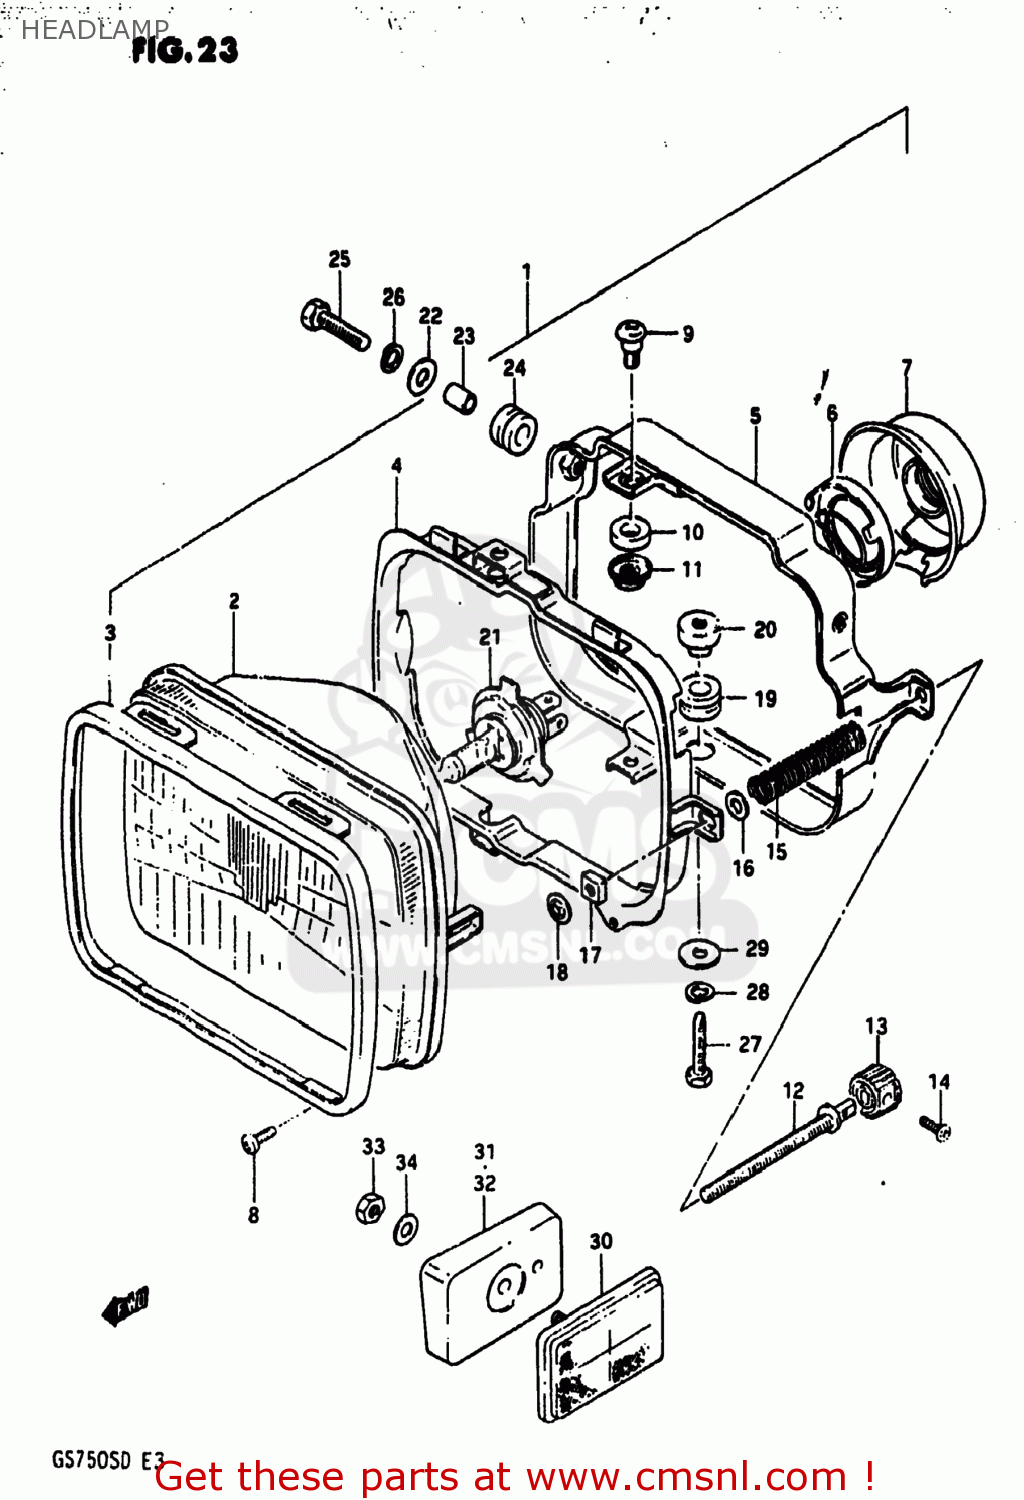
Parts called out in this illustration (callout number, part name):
1	HEADLAMP ASSEMBLY
2	LAMP UNIT
3	RETAINER
4	RING,MOUNTING
5	HOUSING
6	HOLDER
7	COVER,HEADLAMP SOCKET
8	SCREW
9	SCREW
10	SPACER
11	NUT,ADJUSTING
12	SCREW,ADJUSTING
13	KNOB,ADJUSTER
14	SCREW
15	SPRING
16	WASHER
17	NUT
18	NUT,HEADLAMP ADJUSTER
19	CUSHION
20	NUT
21	BULB(12V60/55W,H4)
22	WASHER
23	SPACER (6.1X8X9.5)
24	CUSHION
25	BOLT
26	LOCK WASHER
27	SCREW(6X20)
28	LOCK WASHER
29	WASHER 6MM
30	REFLECTOR,REFLEX
31	SPACER,FRONT REFLEX REFLECTOR
32	SPACER,FRONT REFLEX REFLECTOR
33	NUT
34	WASHER
